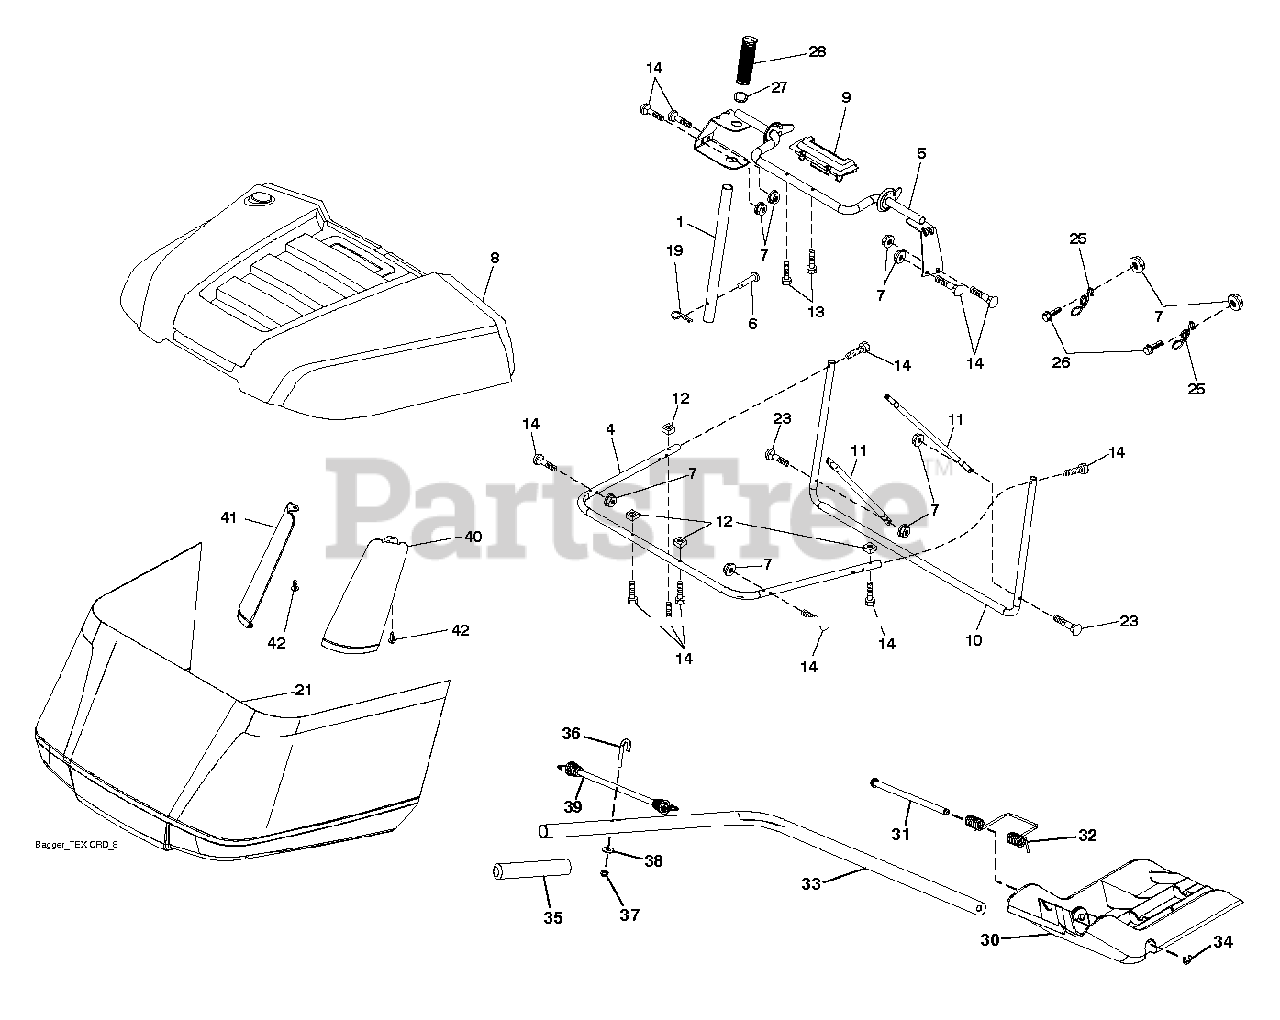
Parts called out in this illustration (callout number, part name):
1	TUBE.HANDLE.BAGGER.CRD/SRD.BLA
4	SUBASM.TOP.TUBE.TEX.CRD
5	FRAME.ASM.TOP.BAGGER.SRD
6	RIVET,DRILLED
7	NUT T
8	BAGGER.TOP.SRD.APPLIQUE
9	INSERT.HANDLE.BAGGER.(2 2)
10	FRAME FRAME.FRONT.TEX.CRD
11	BRACE BRACE SIDE TUBE
12	NUT.SQUARE.1/4
13	SCREW.1/4X1.150.HXWSH
14	BOLT.SHOULDER.HX.WSH.1/4X1.150
19	PIN.COTTER.5/16.BOW TI
25	SPRING.LATCH.BAGGER.SRD
26	SCREW HEX CRT
27	RB GROMMET.RUBBER.SRD
28	GRIP.HANDLE.BLACK
30	PLUG PLUG
31	PIN PIN.HINGE
32	SPRING SPRING DOUBLE TORSION
33	SHAFT SHAFT TEX CRD MULCH PLU
34	E-RING.5/16"
35	GRIP GRIP MULCH PLUG HAND
36	BOLT BOLT J
39	BUBGEE BUBGEE TEX CRD
42	CLIP CHRISTMAS TREE CLIP
